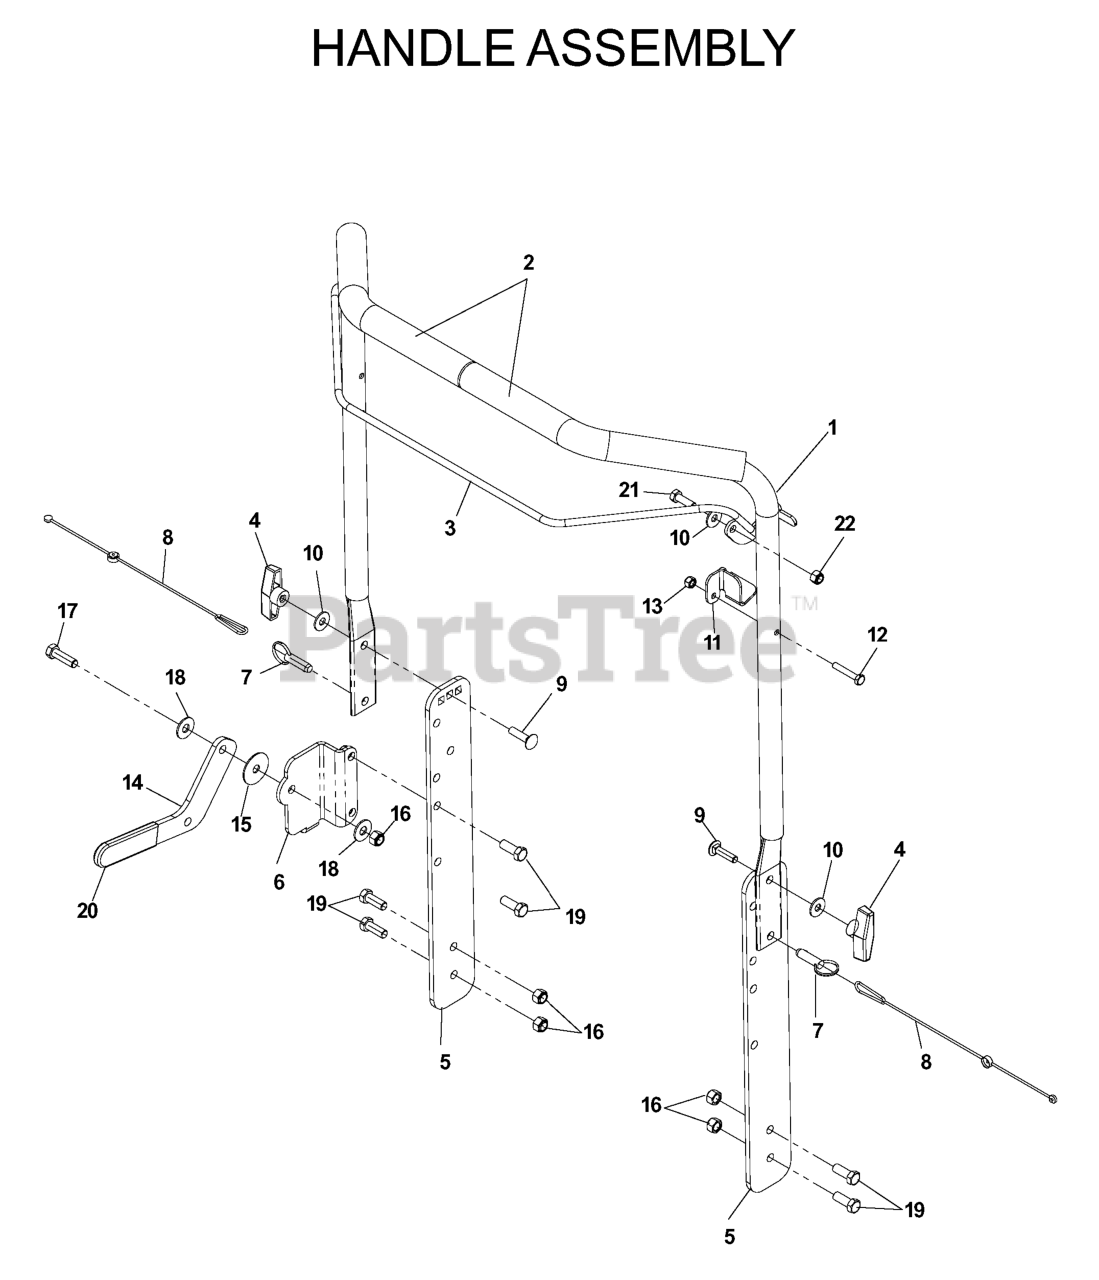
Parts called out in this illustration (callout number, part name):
1	HANDLE GRAY
3	BAIL - ORANGE
5	HANDLE SIDE GRAY
7	DETENT PIN RAKE/DT
9	BOLT, CARRIAGE 5/16X1-1/4
10	WASHER 5/16 FLAT
11	CABLE TAB POWER RAKE
12	SCW 1/4-20 X 1-1/2 HEX
13	NUT.1/4-20.HEX.NYLOC.ZD
15	WASHER, FRICTION
16	NUT 3/8-16 NYLOC
17	HCS 3/8C X 1 1/4 GR5
18	WASHER 3/8 FLAT
19	HCS 3/8-16X1.GRD.5.ZD
21	HCS 5/16C X 1
22	NUT 5/16 NYLOC
